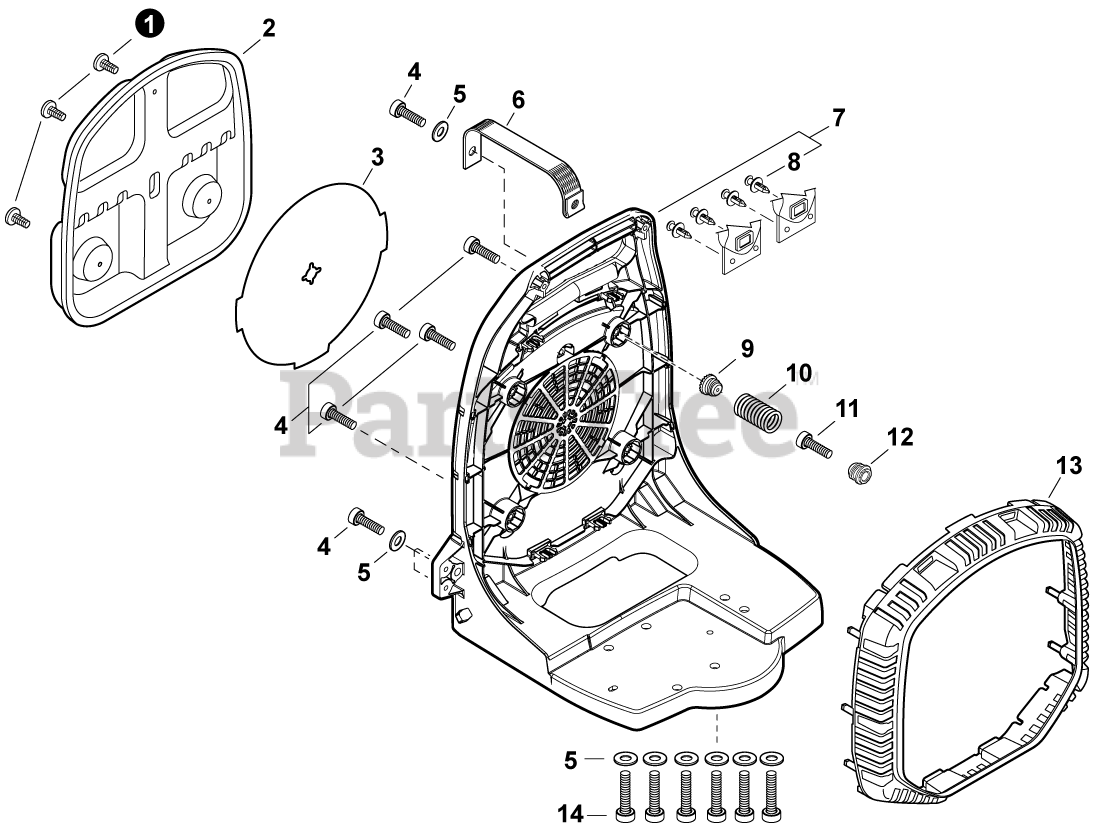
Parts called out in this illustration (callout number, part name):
2	CUSHION, BACKPACK
3	INSERT, COLD WEATHER
4	BOLT, TORX 5x20
5	WASHER 5.5x16x2T
6	STRAP, SAFETY 1.2x100
7	FRAME, BACKPACK WITH CLIPS
9	HOLDER, SPRING
10	SPRING, COMPRESSION
11	BOLT, TORX 5x16
12	HOLDER, SPRING
13	GUARD, DEBRIS
14	SCREW 5x25
